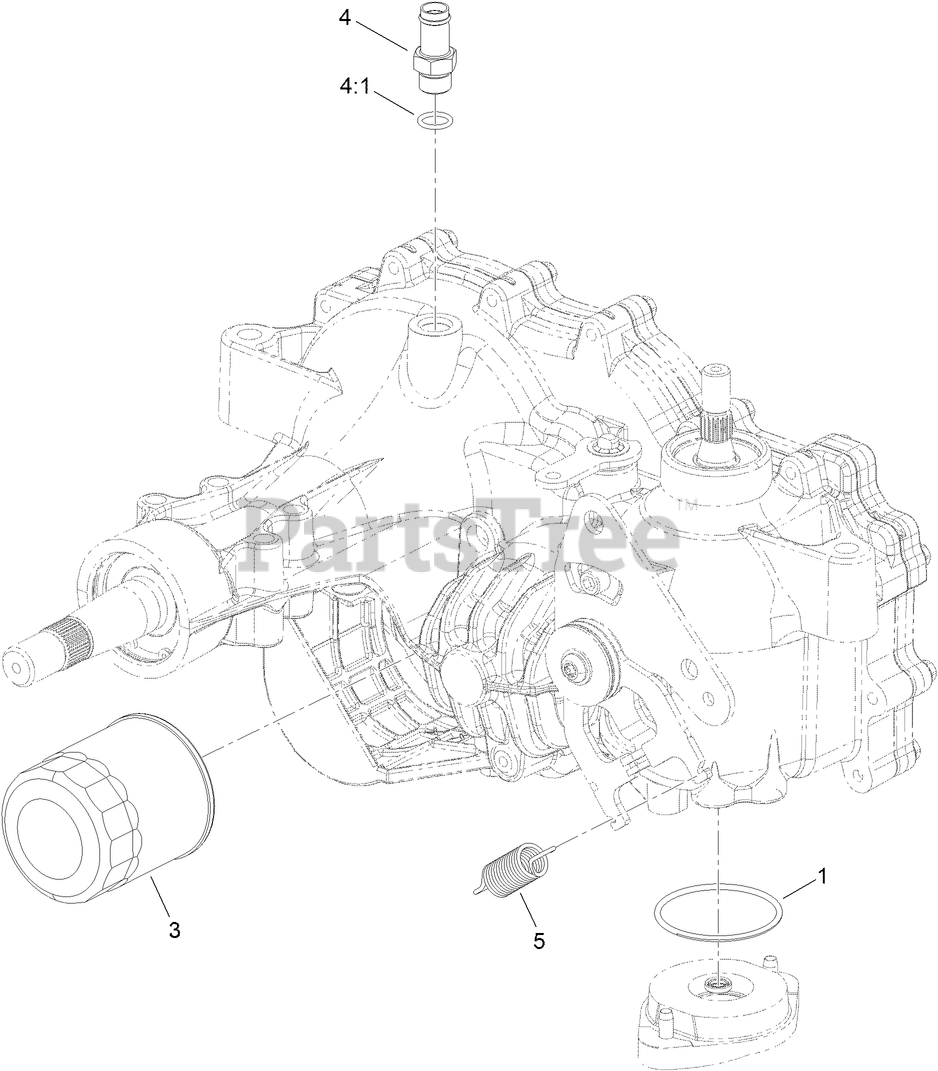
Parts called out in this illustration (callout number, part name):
1	O RING-SEAL
3	ELEMENT-OIL FILTER, HYD
4	ADAPTER-STRAIGHT
4:1	O-Ring
5	SPRING-EXTENSION
